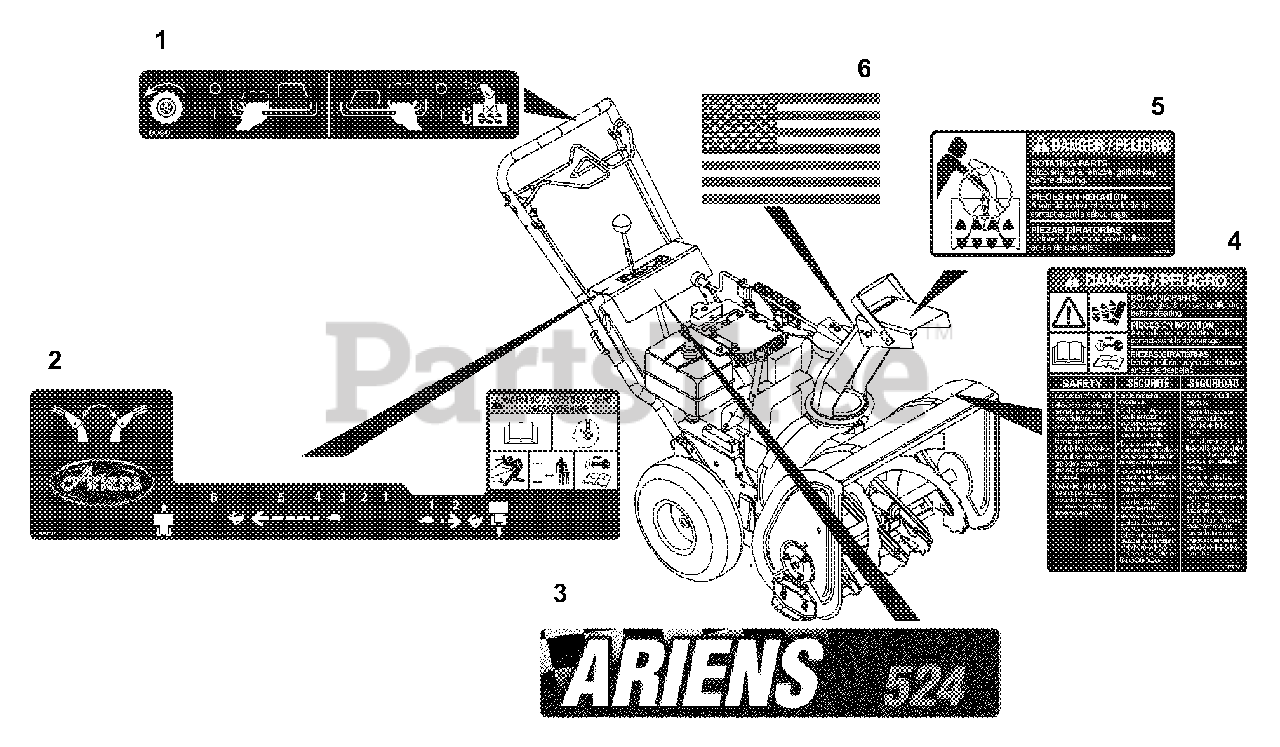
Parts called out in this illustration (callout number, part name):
1	DECAL, BAIL
2	DECAL, CONTROL PANEL
3	DECAL, ST524
4	DECAL, DANGER
5	DECAL, DANGER - ROT. PARTS
6	DECAL, AMERICAN FLAG
